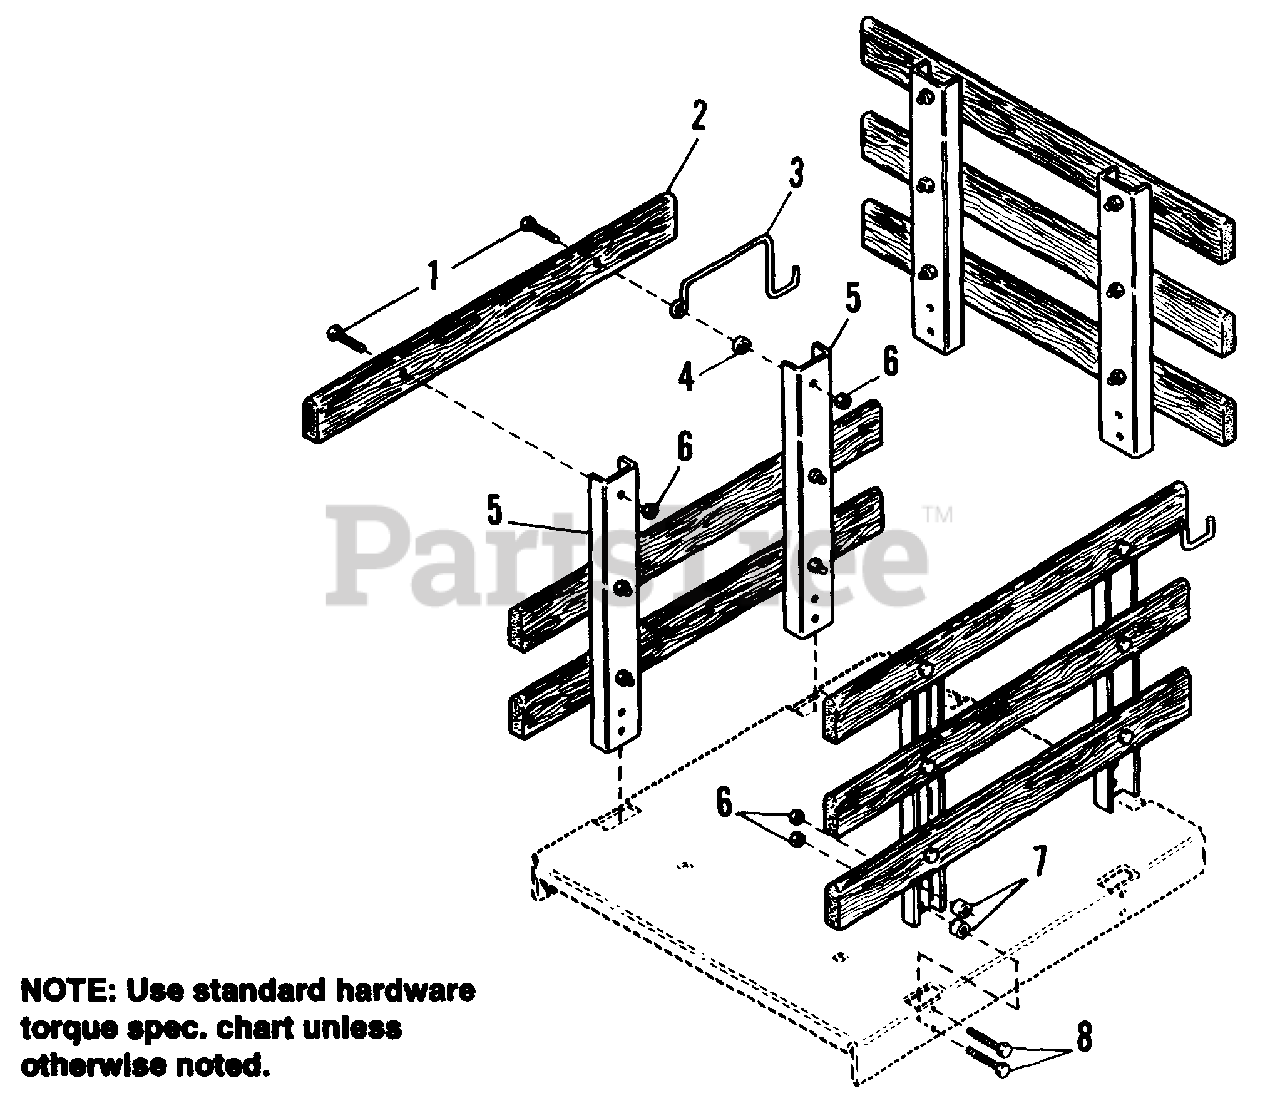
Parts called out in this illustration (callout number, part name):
1	CAPSCREW,1/4-20 x 1-1/2
2	WOOD-GATE
3	LATCH-GATE
6	NUT, Hex Lock, 1/4-20
8	CAPSCREW, 1/4-20 x 1.00
